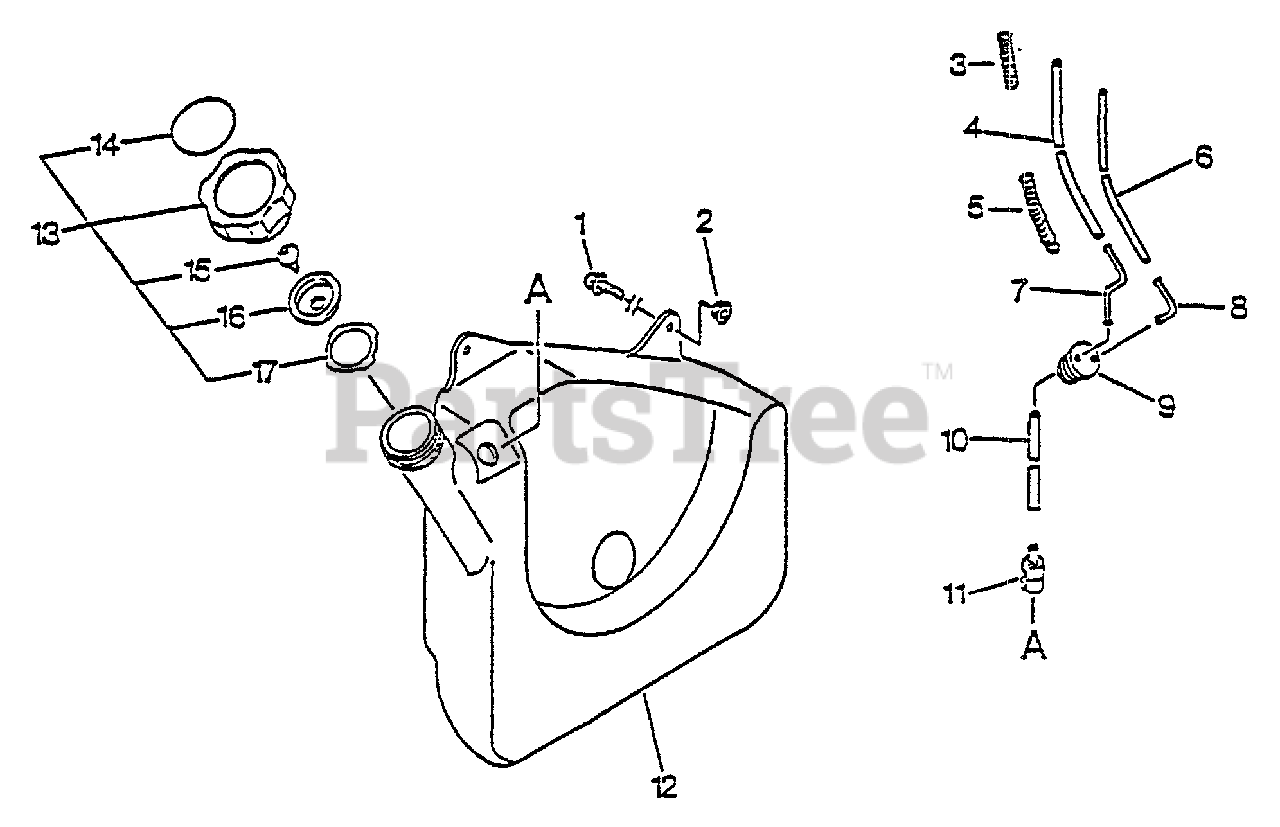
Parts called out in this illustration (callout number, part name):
1	SCREW - 5X14
2	NUT - 5 -- FLANGE
3	WRAP, SPIRAL
4	PIPE - 3X7X520 -- BLACK
5	WRAP, SPIRAL - 130mm
6	PIPE - 2X4X480 -- CLEAR
7	CONNECTOR, PIPE
8	CONNECTOR, PIPE
9	GROMMET
10	PIPE - 3X6X280 -- BLACK
11	FILTER, FUEL
12	TANK, FUEL
13	CAP ASSY
14	LABEL - FUEL MIX
16	HOLDER, VENT
17	GASKET, CAP
